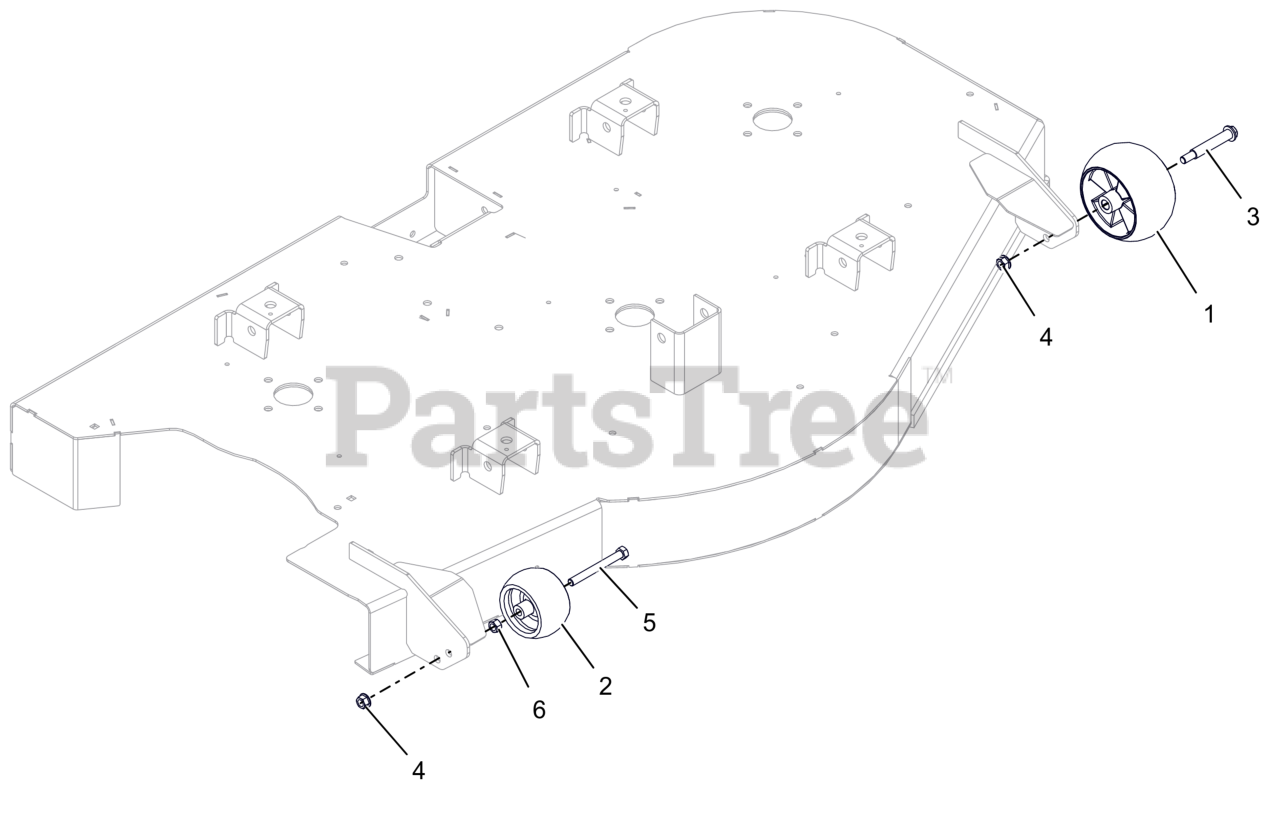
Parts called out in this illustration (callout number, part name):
1	ANTI-SCALP WHEEL - 5X OS
3	BLT-SHLDR .38-16X2.50 HWH G5
4	NUT-LK-CTR-FLG .375-16 GF ZCC
5	BLT, HEX .38-16X3.50 G5 ZCC
6	NUT-STD .375-16 G2 ZCC
